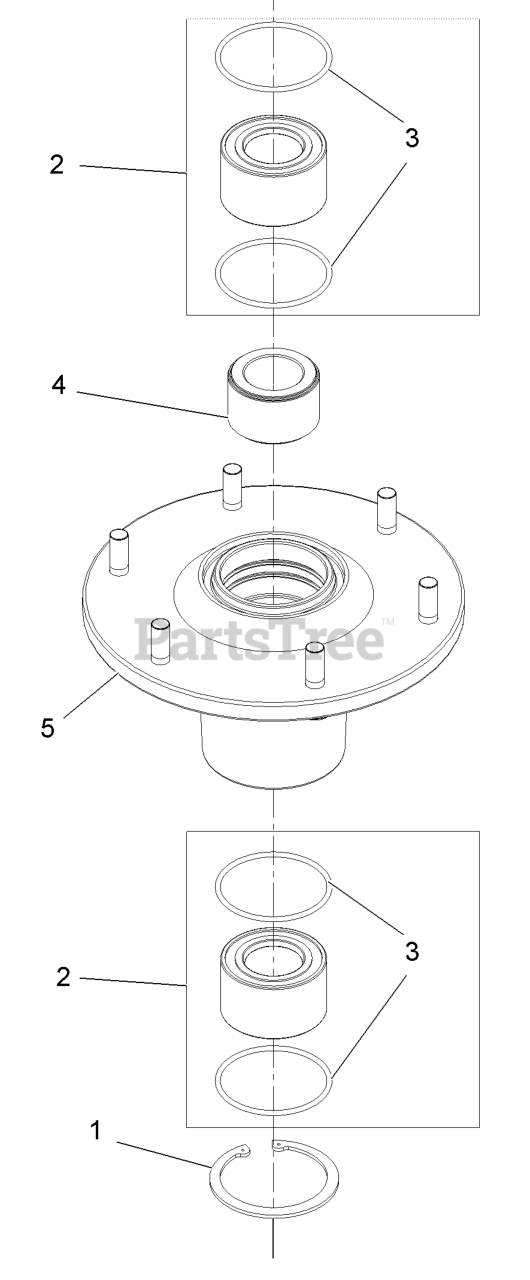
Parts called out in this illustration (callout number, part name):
1	RING-RETAINING
2	ASM, BEARING W/ORINGS
4	SPACER,BEARING
5	ASM,HOUSING W/STUDS
